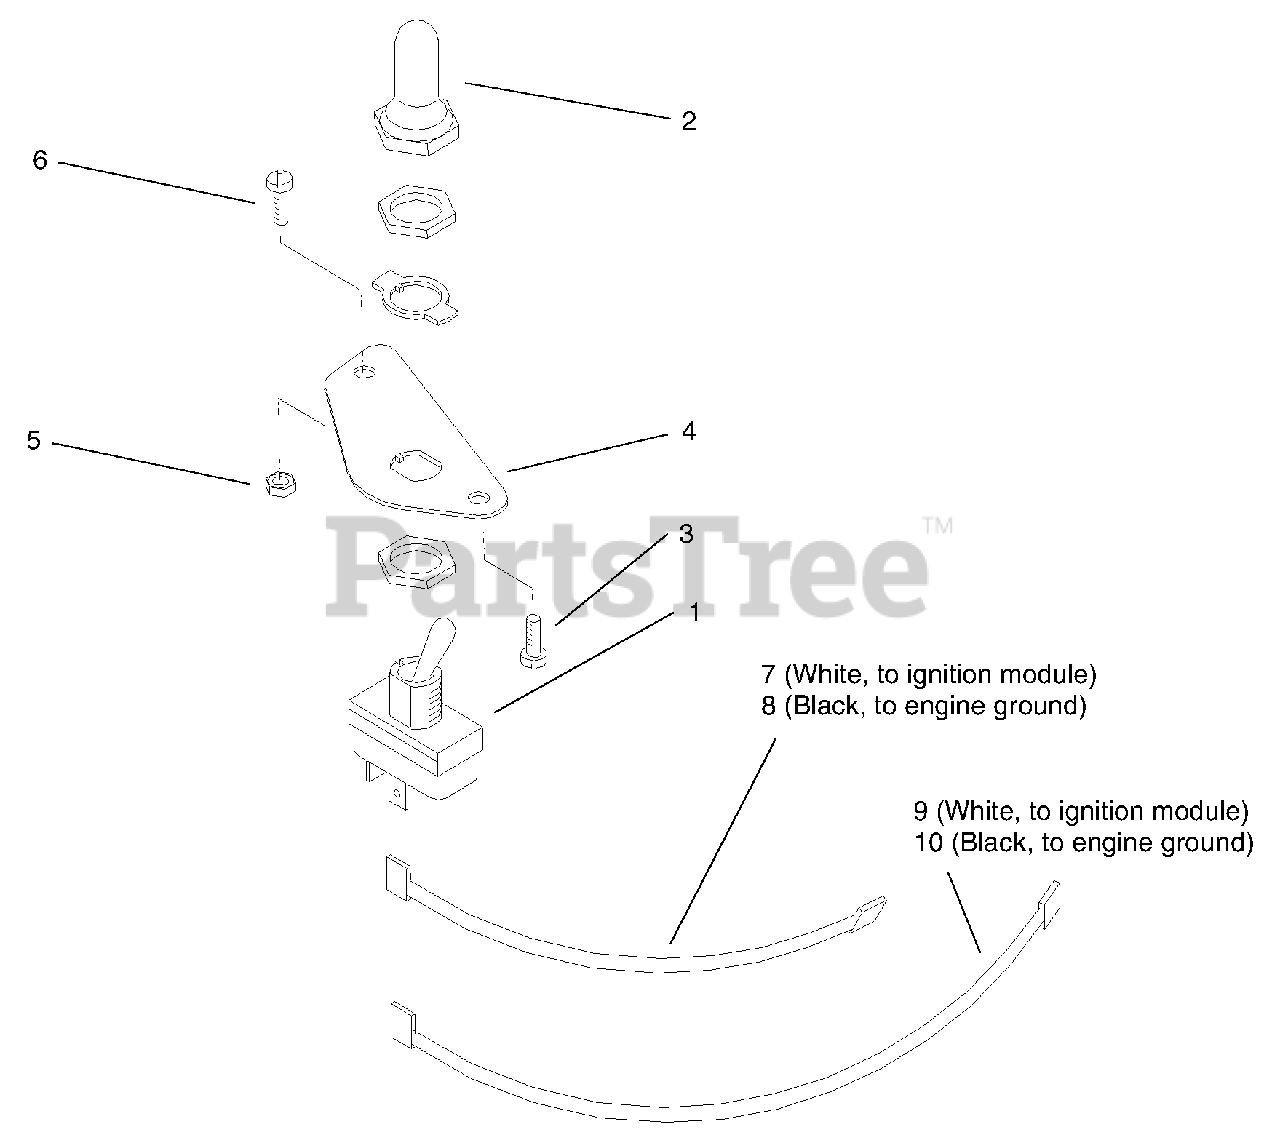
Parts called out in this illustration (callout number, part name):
1	Switch ASM
2	Boot-Switch
3	Screw-PPH
4	Plate-Switch Mounting
5	Nut-Lock
6	Screw-PPH
7	Wire-Kill 8"
8	Wire-Ground 8"
9	Wire-Kill 14"
10	Wire Ground 14"
